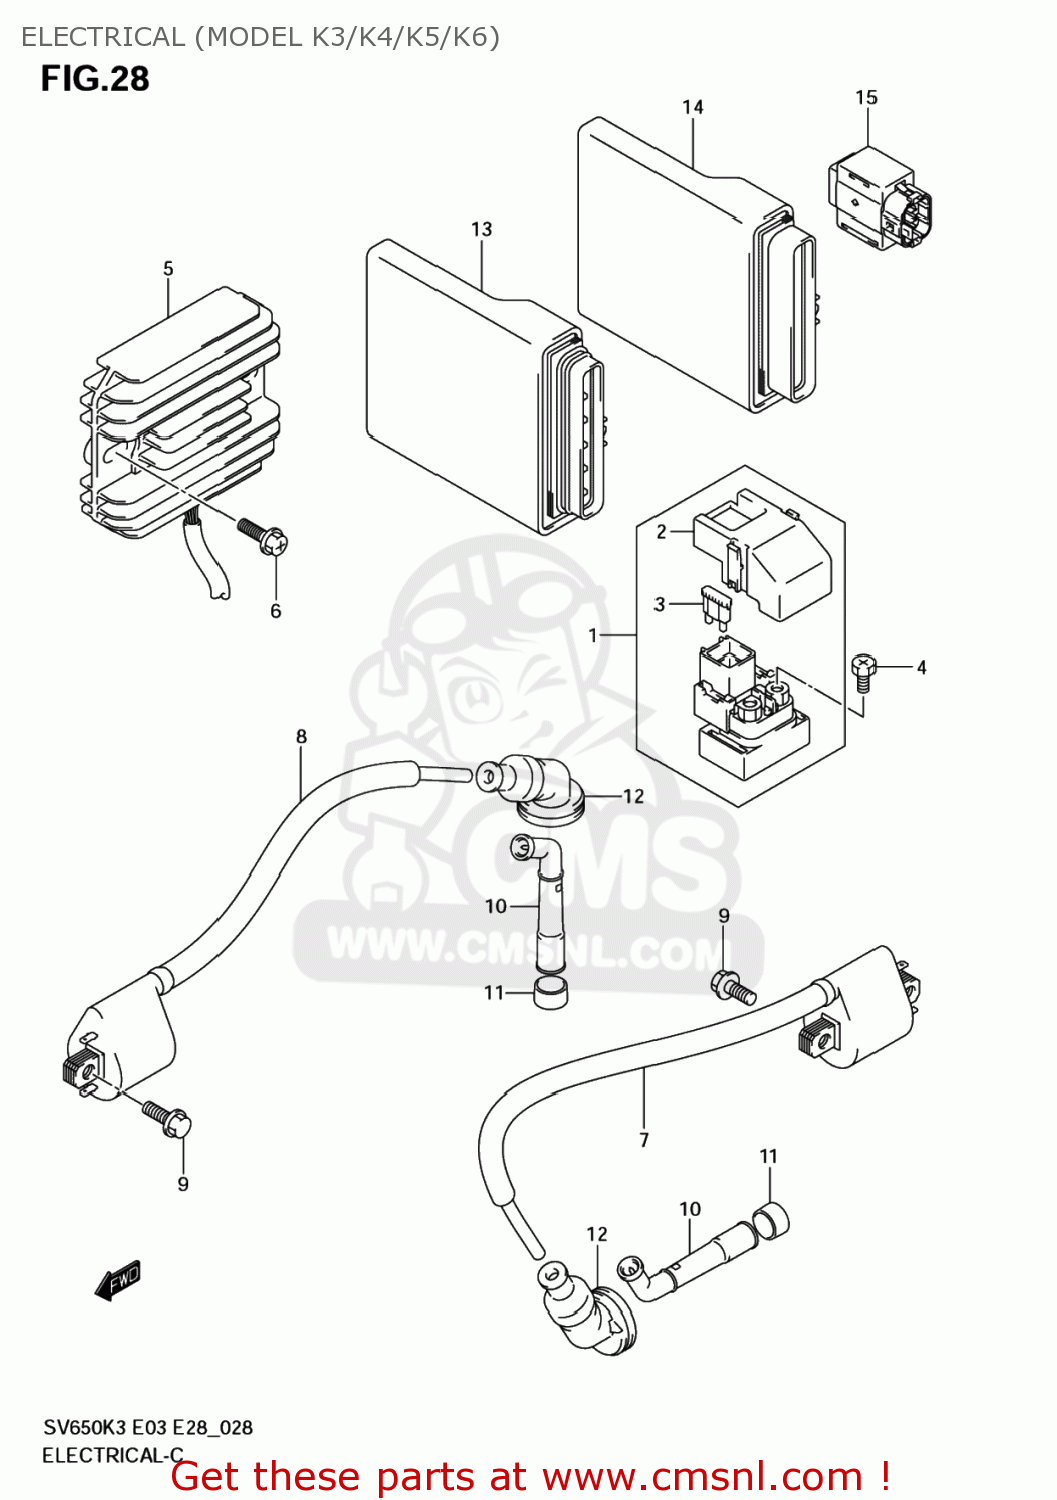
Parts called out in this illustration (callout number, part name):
1	RELAY ASSY,STARTING MOTOR
2	COVER
3	FUSE(30A)
4	SCREW(6X8)
5	RECTIFIER ASSY
6	SCREW
7	COIL ASSY,IGNITION
8	COIL ASSY,IGNITION
9	SCREW
10	CAP ASSY,SPARK PLUG
11	SEAL,SPARK PLUG CAP
12	SEAL,HIGH TENS
13	CONTROL UNIT,FI
14	CONTROL UNIT,FI
15	SENSOR ASSY,FUEL CUT
